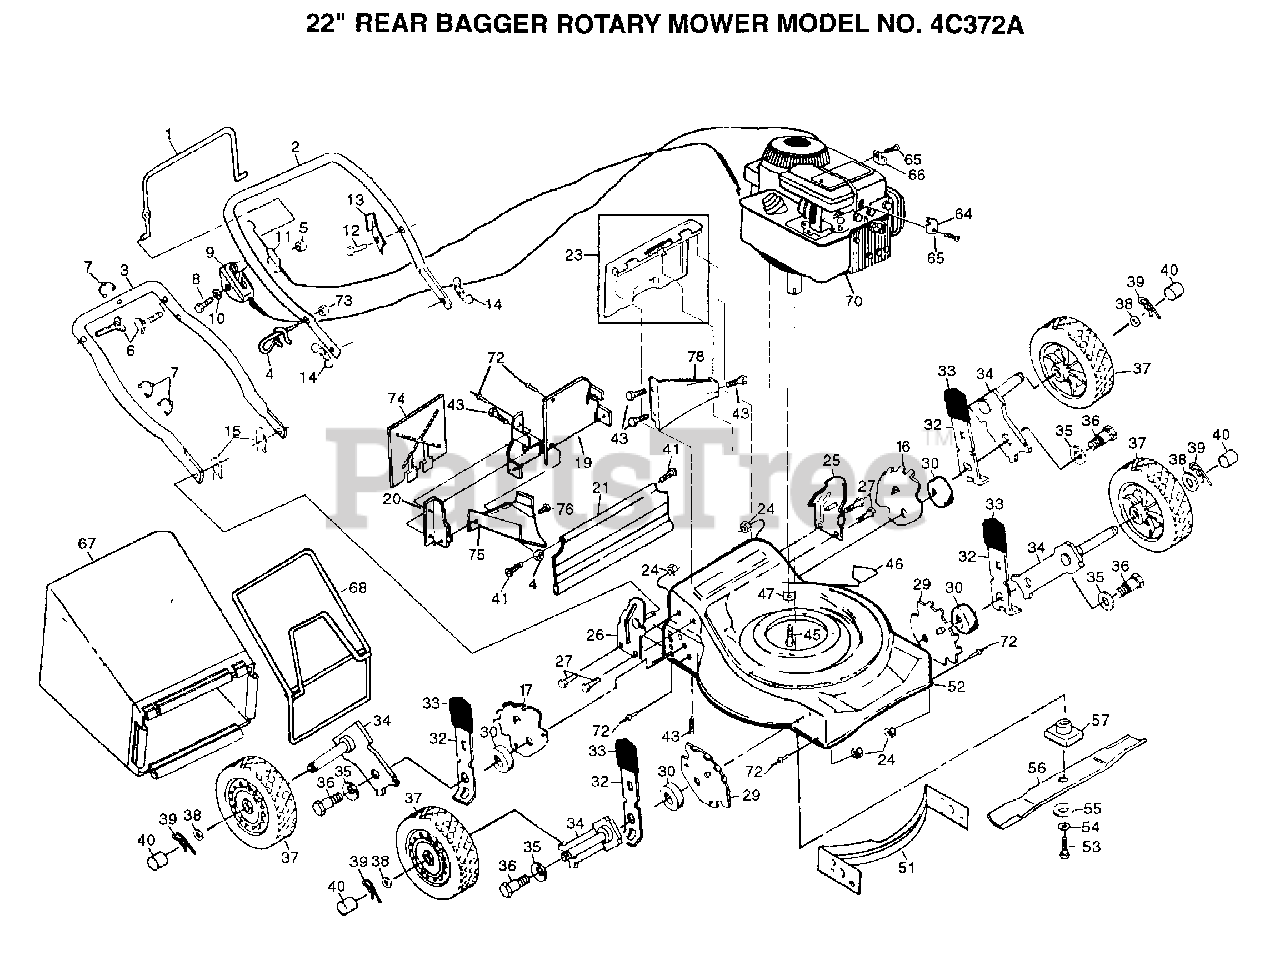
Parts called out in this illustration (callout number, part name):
1	CONTROL BAR
4	ROPE GUIDE
6	BOLT.HANDLE.LM
9	CONTROL THROTTLE
10	WASHER PM
11	"CABLE,ENG ZONE CO"
12	TAPPING SCREW
13	"BRKT,UPSTOP"
14	"NUT,WING PM"
15	HAIRPIN COTTER
19	PLATE.BACK
23	"KIT, REAR DOOR PM"
24	LOCKNUT PM
27	SCREW
32	SPRING SELECTOR
33	KNOB PM
34	AXLE ARM
35	"WASHER, BELLEVIL."
38	WASHER
39	RETAINER CLIP PM
40	HUB CAP
41	HINGE SCREW
43	SCREW
45	SCREW
46	DECAL HYT
52	KIT.HSG.22RD.PUSH
53	SCREW
54	LOCKWASHER
55	"WASHER,HARDEN"
57	ADAPTOR.BLADE.LM
64	CABLE CLAMP
65	SCREW PM
66	"CLIP,CABLE"
67	GRASS BAG
68	CATCHER FRAME
72	BLIND RIVET
73	NUT
74	MULCHER PLATE
75	DISCHARGE BAFFLE
76	SCREW PM
78	REAR BAFFLE
